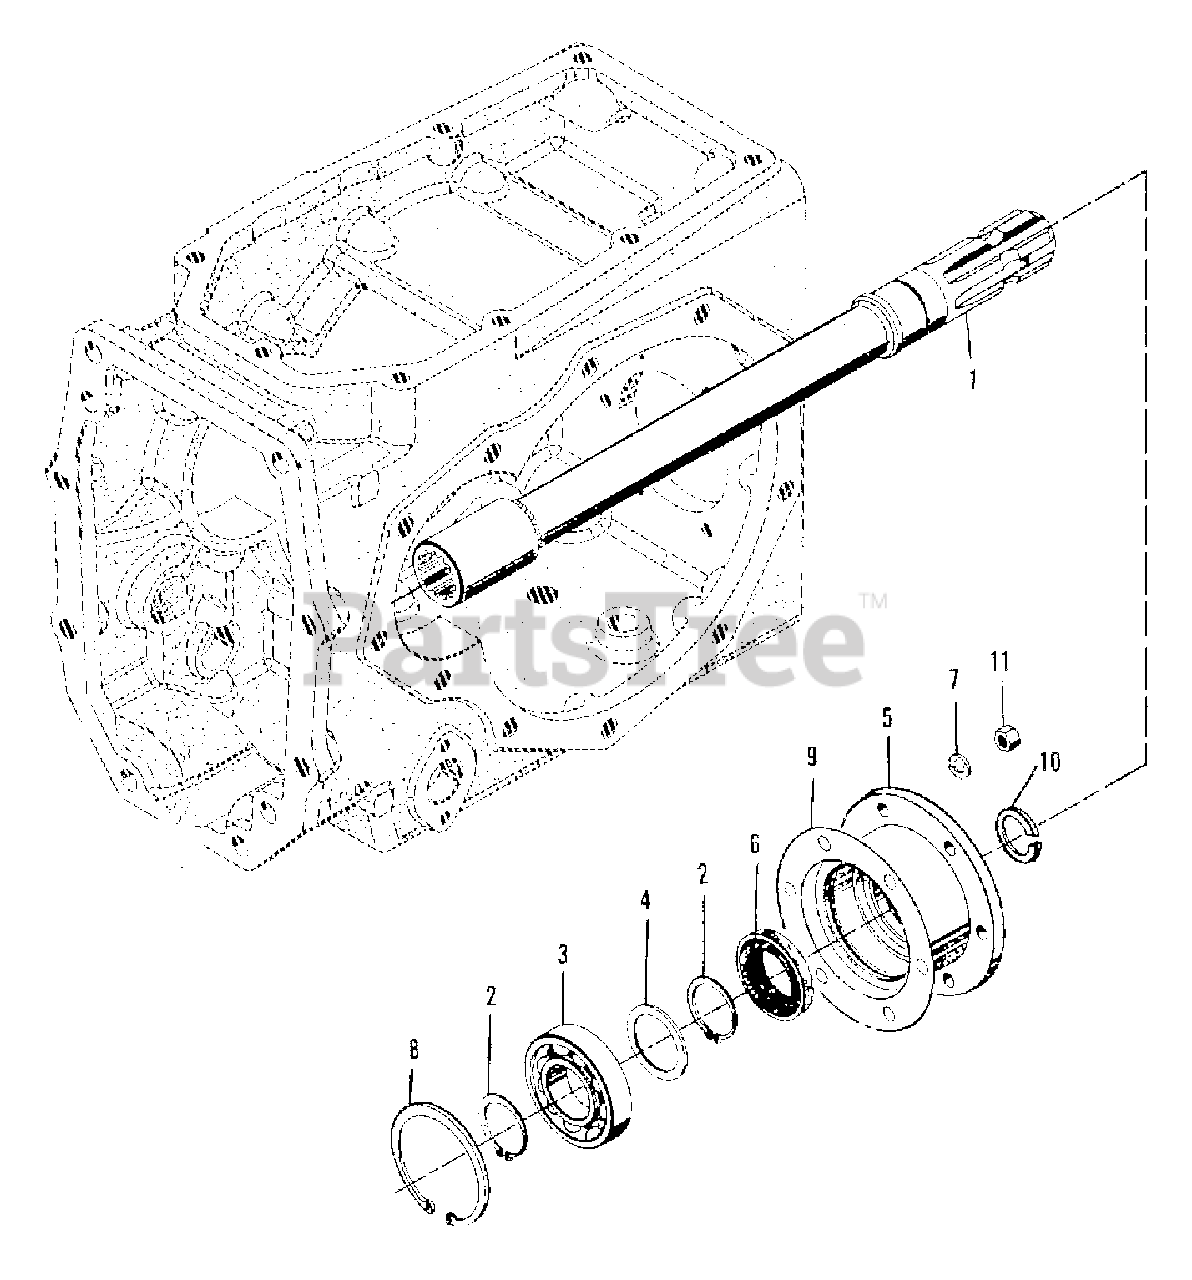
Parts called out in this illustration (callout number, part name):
1	SHAFT, P.T.O. extension
2	RING, M35, snap-exernal
3	BEARING, ball
4	WASHER, thrust
5	RETAINER ASSEMBLY, bearing (Incl. Item 6)
6	SEAL, oil
7	LOCKWASHER
8	RING, M72, snap-internal
10	RING, stop
